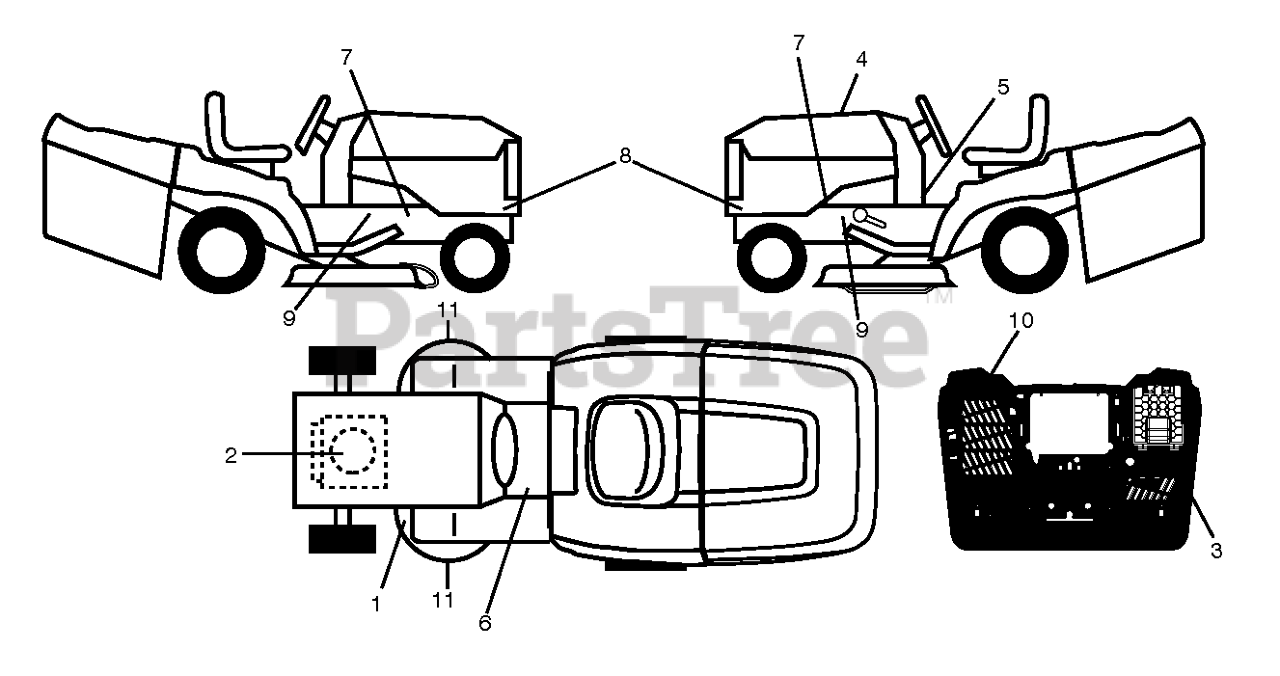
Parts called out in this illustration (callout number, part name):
1	Decals
2	DECAL.ENGINE.WARNING
3	DECAL DECAL.BYPASS.BACKPLATESI
4	Decals
5	DECAL.INSTRUCTION.MLCH/BG.VERT
6	DECAL.TRACTOR.SADDLE
7	DECAL.WARNING.HOT.MUFFLER.2021
7	DECAL.CHASSIS.HOT.MUFFLER
9	DECAL.WARNING.SERVCE/FIRE
10	DECAL DECAL.WARNING.COMBINED.T
11	DECAL.CUTFINGER.CE.02
